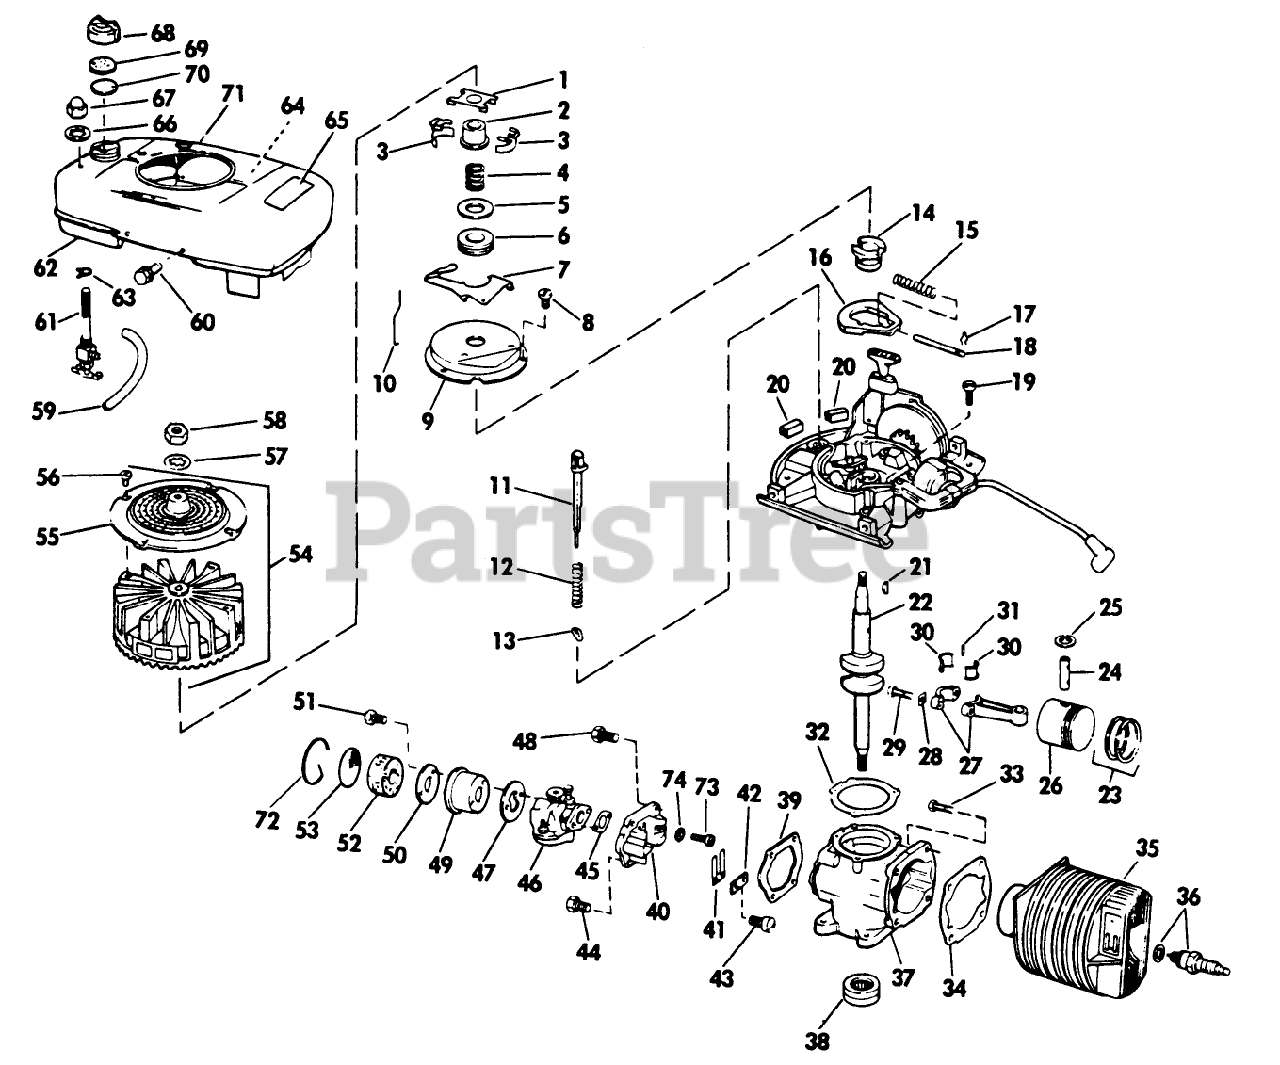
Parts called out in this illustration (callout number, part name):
2	COLLAR S
6	THRUST COLLAR S
7	LEVER-GOVERNOR S
8	SCREW S
9	DUST COVER S
12	SPRING S
14	SPARK ADV. S
15	SPARK ADV. SPRING S
16	FLYWEIGHT S
17	SPARK ADJ. SPRING
18	PIN,SPARK ADV. S
19	SCREW S
25	RING-RETAINING
30	LINER ASM
32	GASKET S
34	GASKET S
36	Spark Plug and Gasket
39	GASKET S
40	REED PLATE AY. S
42	PLATE-BACKUP, REED
44	SCREW S
45	GASKET S
47	GASKET S
48	SCREW S
50	BACK-UP PLATE
52	ELEMENT
54	Flywheel Screen Assy.
56	SCREW F
60	SCREW S
61	VALVE&SCREEN SM
63	CLAMP - HOSE S
67	PALNUT S
68	FUEL CAP AY S
69	GASKET S
70	BAFFLE - FOAM SM
